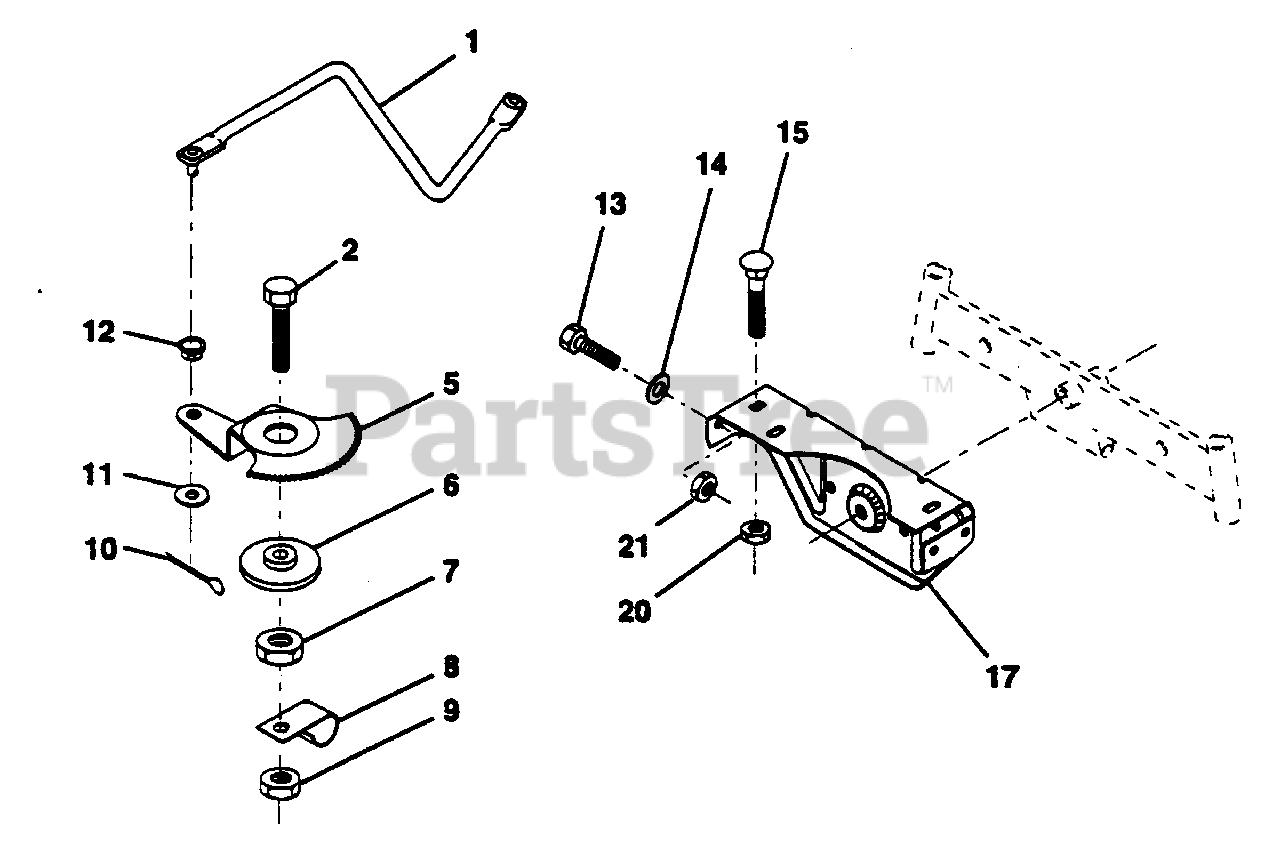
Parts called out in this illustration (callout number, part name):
1	Link, Drag (AYP part number)
2	Bolt, Fin Hex 1/2-13 x 1-3/4 (AYP part number)
5	Gear, Sector (AYP part number)
6	Bushing (AYP part number)
7	Nut, Heavy Hex Top Lock 1/2-13 UNC (AYP part number)
8	Clip, Insulated (AYP part number)
9	Nut, Crownlock 3/8-16 (AYP part number)
10	Pin, Cotter 1/8 x 3/4 (AYP part number)
11	Washer, 13/32 x 13/16 x 16 Ga. (AYP part number)
12	Bushing (AYP part number)
13	Bolt, Hex Hd. 5/16-18 UNC x 3/4 (AYP part number)
14	Washer 11/32 x 7/8 x 16 Ga. (AYP part number)
15	Bolt, Carriage 3/8-16 UNC x 3/4 (AYP part number)
17	Support, Front Axle (AYP part number)
20	Nut, Crownlock 3/8-16
21	Nut, Crownlock 5/16-18
